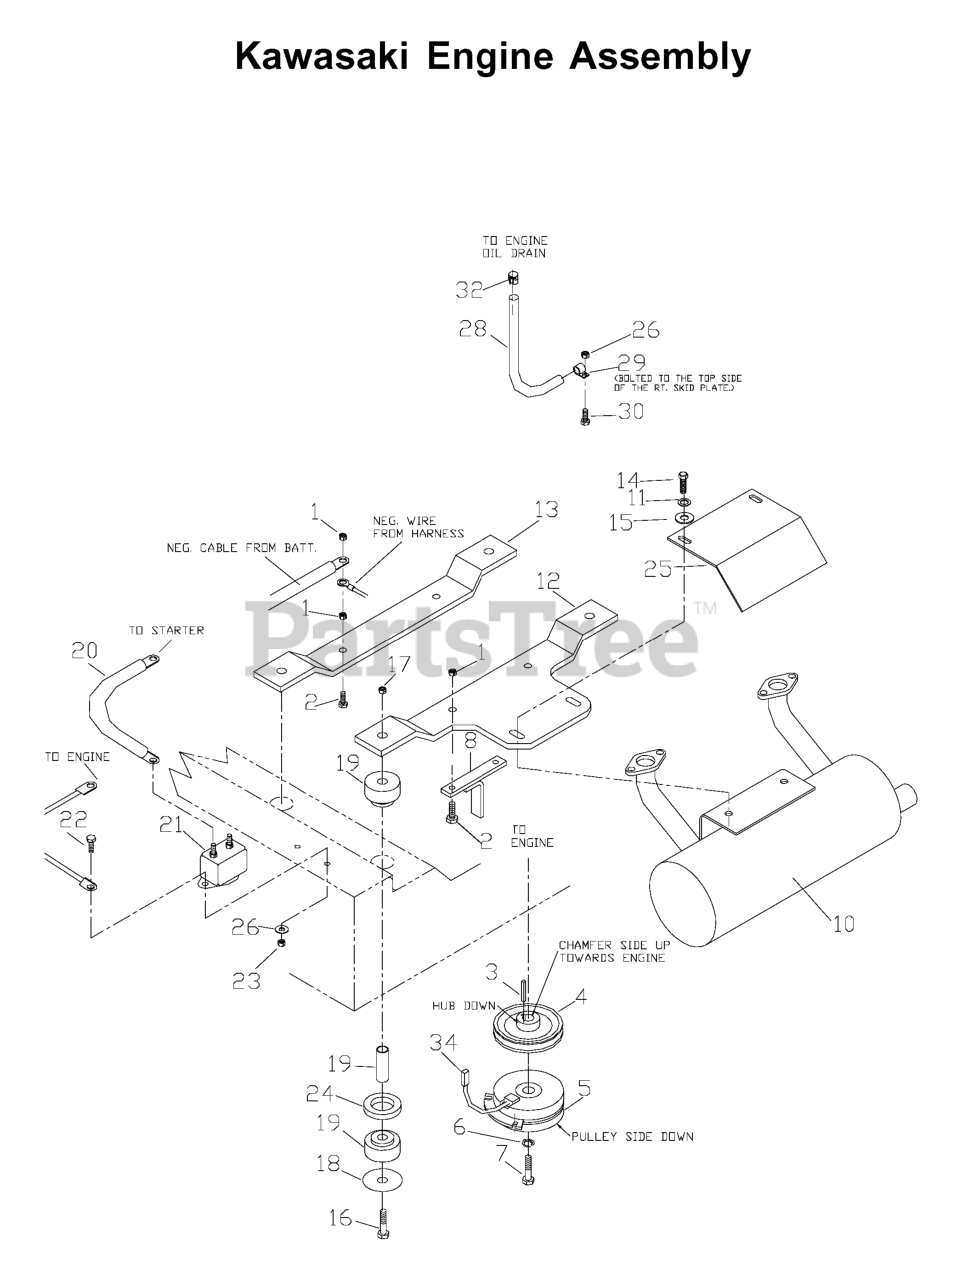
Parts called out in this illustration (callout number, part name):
1	NUT 5/16C CENTERLOCK
2	HCS 5/16C X 1 3/4
3	KEY 1/4" SQ X 1 7/8"
5	ELECTRIC CLUTCH W/CABLE
6	WASHER 7/16 LOCK
7	BOLT 7/16F X 2 1/2
8	CLUTCH TIE DOWN
9	KAW PIGTAIL
10	MUFFLER KAWASAKI GEN II
11	WASHER.LOCK.HVY.HLCL.SPR.5/16
12	REAR ENGINE MOUNT
13	ENGINE MOUNT
14	HCS 5/16C X 3/4
15	WASHER 5/16 FLAT
16	HCS 1/2C X 3 1/4
17	NUT 1/2-13 HEX NYLOC ZD
18	ISOLATOR WASHER
20	CABLE POSITIVE
22	HCS 1/4C X 5/8
23	NUT 1/4C CENTER LOCK
24	ISOLATOR SPACER
25	MUFFLER GUARD
26	WASHER 1/4 INT TOOTH
27	GROUND WIRE (KAW)
28	OIL DRAIN HOSE (KAW)
30	HCS 1/4C X 3/4 HCS
31	CHOKE CONTROL, COMPLETE
34	CLUTCH HARNESS
